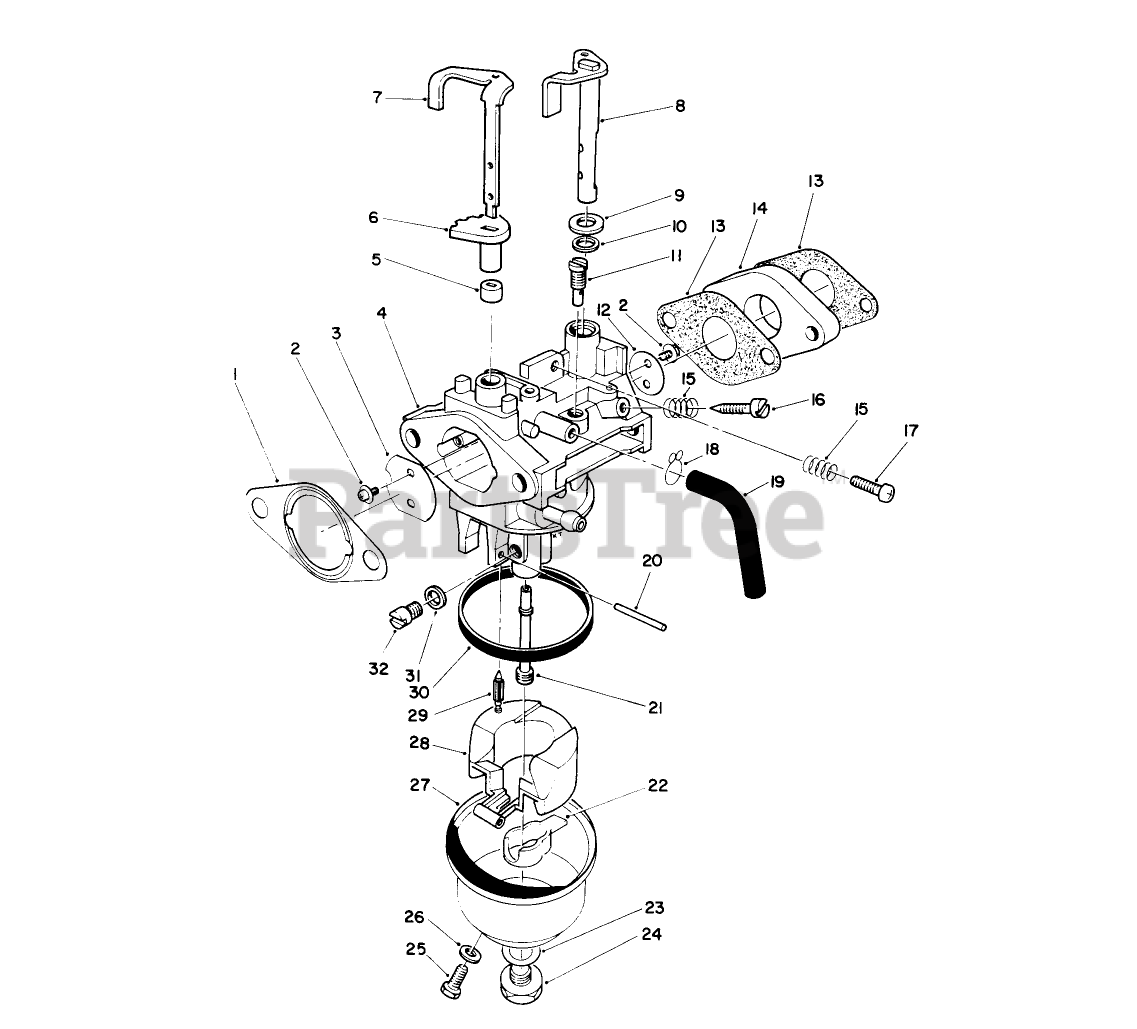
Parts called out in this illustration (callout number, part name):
1	GASKET F/W ENGINE
3	VALVE
4	Body-Carburetor
5	Shaft-Choke Valve
10	VALVE
11	GASKET INTAKE
13	SPRING-PILOT SCREW
14	ADJUSTER
16	SCREW
22	GASKET
23	SCREW
24	SCREW
25	GASKET
27	FLOAT
29	FLOAT BOWL GASKET
31	JET-HIGH ALTITUDE
32	LOWER CHOKE RING
33	UPPER CHOKE RING
